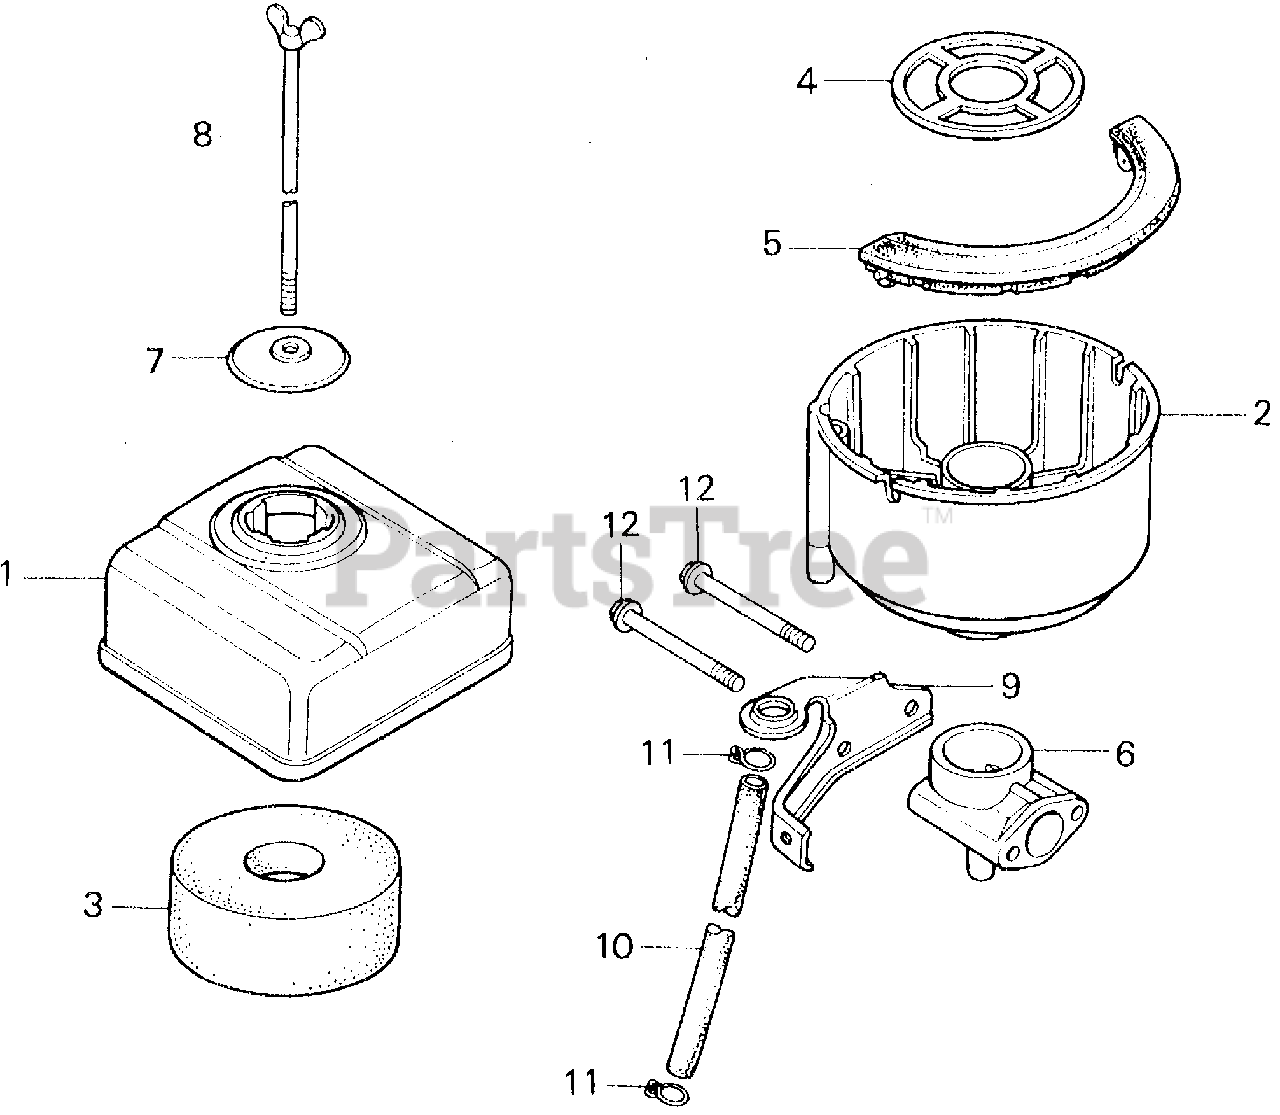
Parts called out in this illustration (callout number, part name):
1	BODY, AIR CLEANER *NH31* (MCKINLEY WHITE) (NOT AVAILABLE)
2	PAN, AIR CLEANER OIL
3	ELEMENT, AIR CLEANER
4	GRID, AIR CLEANER
5	GASKET, OIL CLEANER
6	ELBOW, AIR CLEANER
7	CAP, AIR CLEANER
8	BOLT, AIR CLEANER
9	STAY, AIR CLEANER
10	BULK HOSE, FUEL (8X1000) (8X250)
11	CLIP, TUBE (B12.5)
12	BOLT, FLANGE (6X70)
